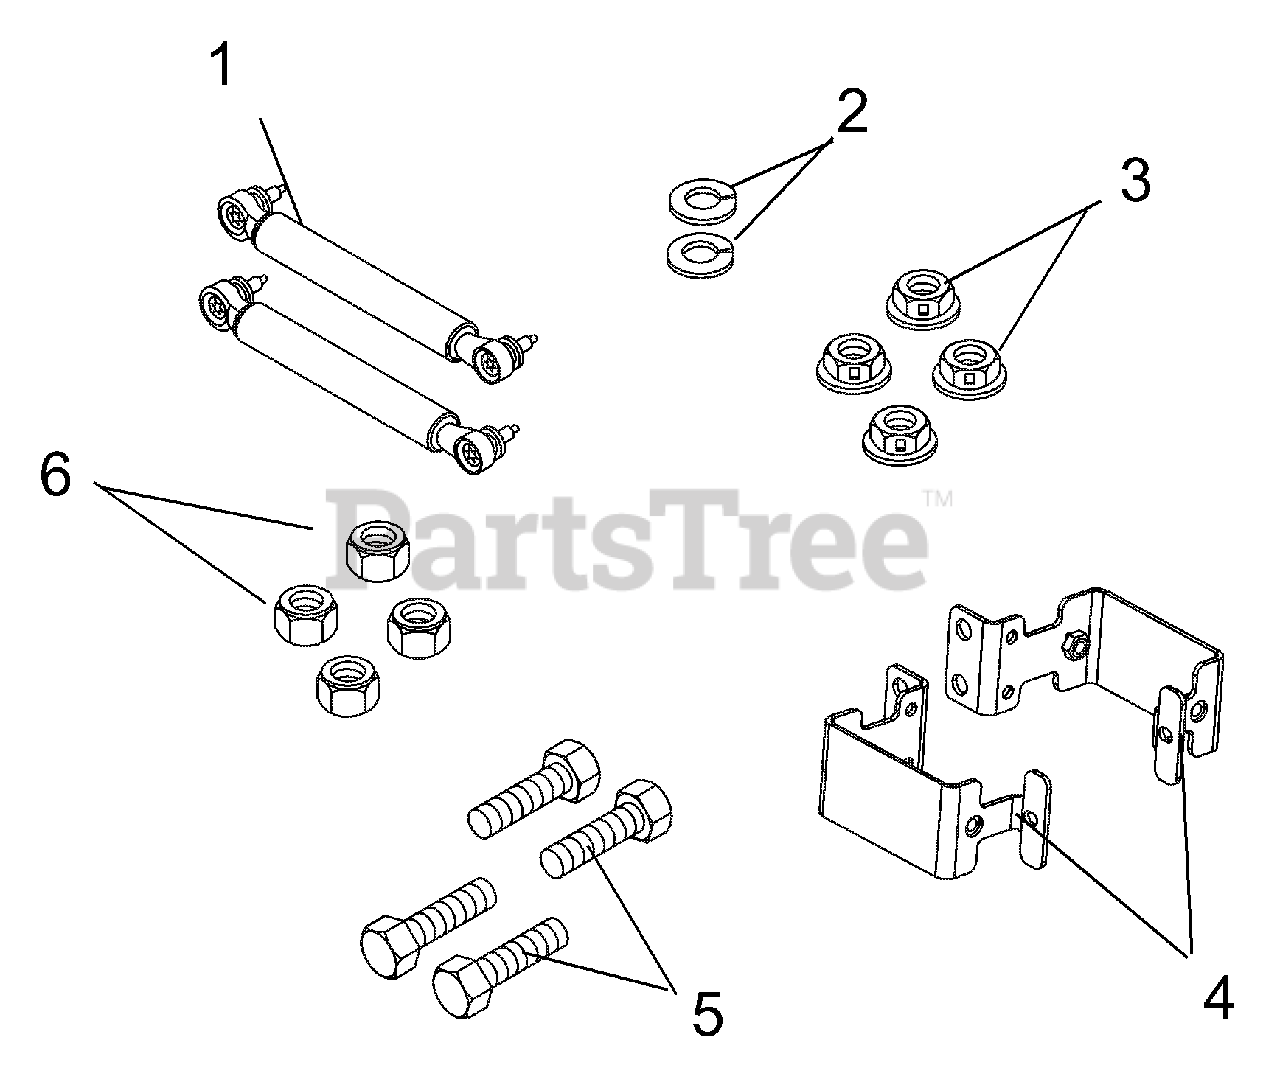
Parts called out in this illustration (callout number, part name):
2	@WSHR-LK .31X.078 REG YWZC
3	NUT, TOP LOCK FLG 8X1.25 YWZC
4	WMT, STEERING STOP
5	BLT-HEX .38-16X2.0 GR5 FTD YWZ
6	NUT-HEX-JAM .375-16 YWZC
